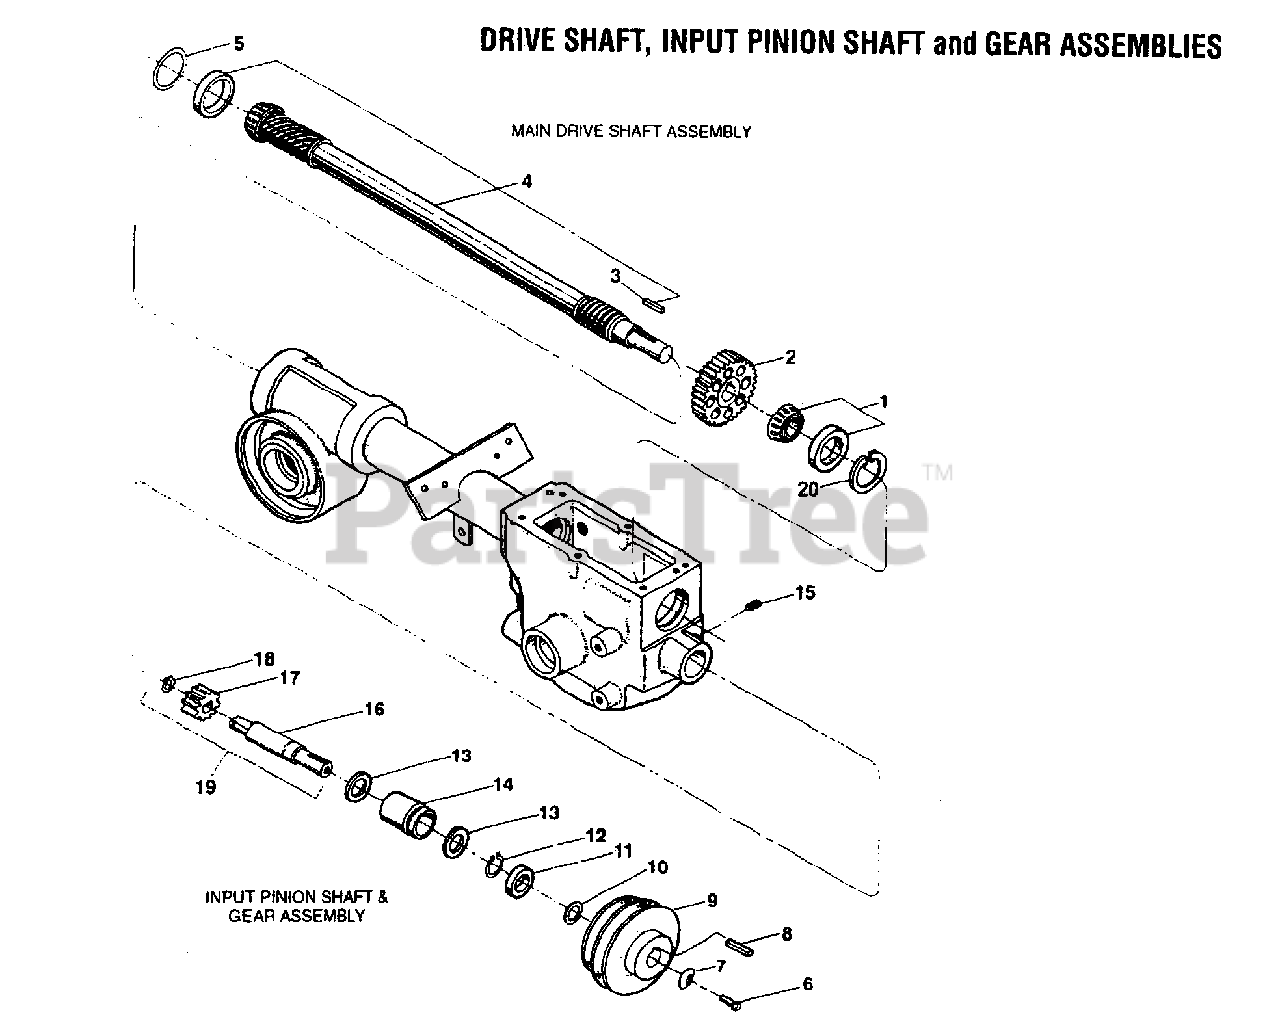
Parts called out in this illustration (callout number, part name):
1	Bearing, Tapered Roller with Race
2	Spur Gear
3	Key, 3/16 sq. x 1
4	Main Drive Shaft
5	Shim, Rear Bearing Cap, .010" thick
5	Shim, same as above, but .030" thick
5	Shim, same as above, but.005" thick
6	Hex Hd. Screw, 5/16-24 x 1-1/8
7	Washer, Disc Spring (concave surface faces pulley)
8	Key, 3/16 sq. x 1-1/2
9	Transmission Drive Pulley
10	Support Washer
11	Oil Seal, Input Pinion Shaft
12	Retaining Ring (external)
13	Thrust Washer
14	Bushing
15	Set Screw, 5/16-18 x 3/8
16	Input Pinion (steel shaft)
17	Input Pinion Gear
18	Retaining Ring (external)
19	Pinion Assy.
20	Retaining Ring (internal)
